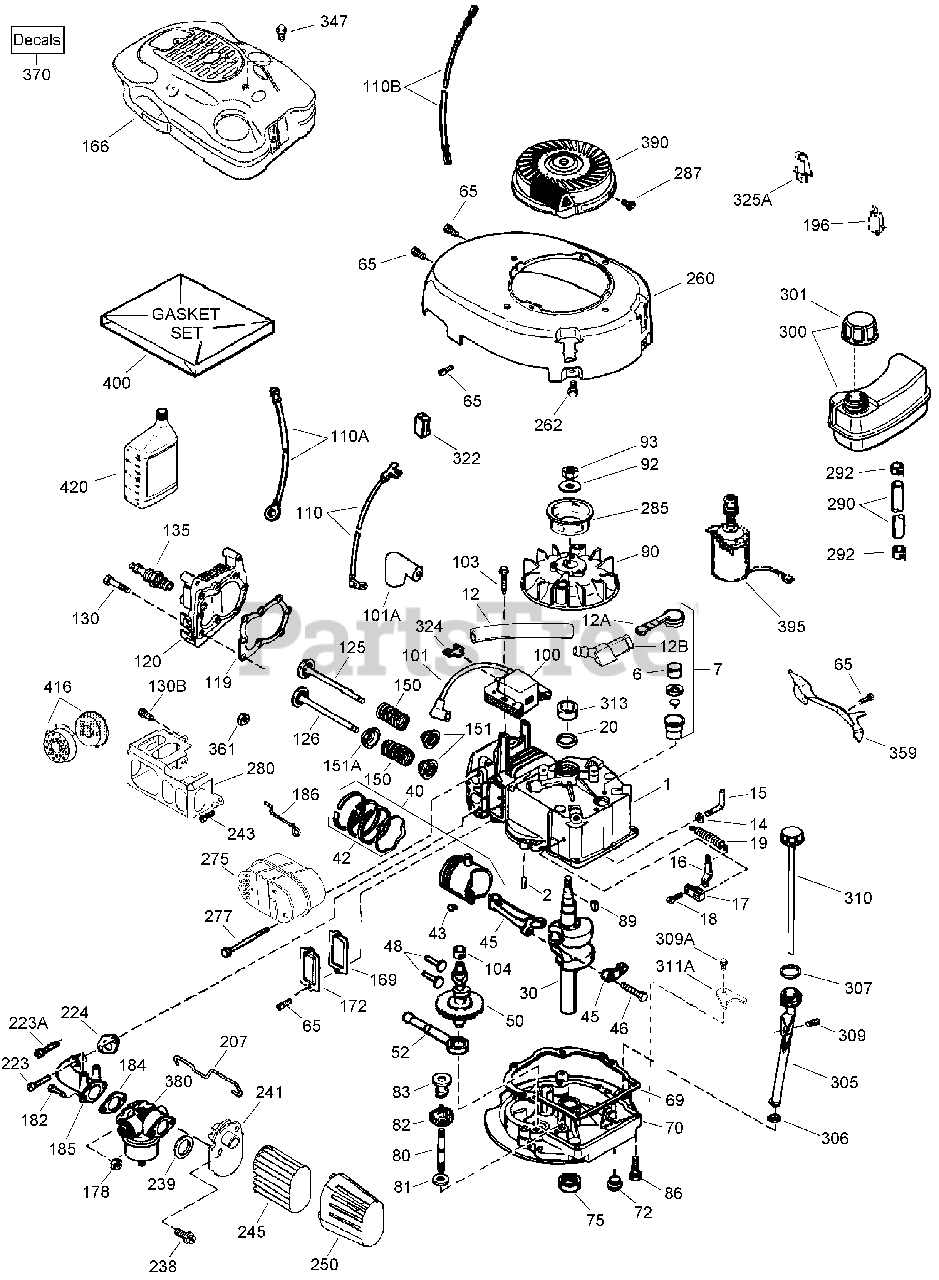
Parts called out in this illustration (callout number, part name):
150	Spring-Valve
151	Cap-Valve, Spring
151A	Seal-Valve, Intake
166	Shroud-Engine (Green)
169	Gasket-Cover, Valve
172	Cover-Valve
178	Nut and Lock Washer (1/4-28)
182	Screw (1/4-28 x 7/8)
184	Gasket-Carburetor To Intake Pipe
185	Pipe-Intake
186	Link-Governor
196	Switch-Restart, Power
207	Link-Throttle
223	Screw (1/4-20 x 1)
223A	Stud-Pipe, Intake
224	Gasket-Pipe, Intake
238	Screw (10-32 x 49/64)
239	Gasket-Air Cleaner
241	Collar-Air Cleaner
243	Screw (10-32 x 7/16)
245	Filter-Air Cleaner (also available in Packaged Part 740083)
250	Cover-Air Cleaner
260	Housing-Blower
262	Screw (1/4-20 x 1/2)
275	Muffler
277	Screw (1/4-20 x 2-9/32)
280	Shield-Heat
285	Cup-Starter
287	Screw (8-32 x 21/64)
290	Line-Fuel (Low Permeation)
292	Clamp-Line, Fuel
300	Fuel Tank ASM (Includes 292 and 301)
301	Cap-Fuel (Black) (1-1/2 ID) (also available in Packaged Part 740041B)
305	Tube-Fill, Oil
306	O-Ring
307	O-Ring
309	Screw (10-32 x 1/2)
309A	Screw (10-24 x 3/4)
310	Dipstick
311A	Bracket-Holddown
313	Spacer
322	Body-Connector
324	Terminal
325A	Clip-Actuator, Brake Switch
347	Screw (10-32 x 27/32)
359	Guard-Flywheel
361	Nut-Lock
370	Decal-Primer
370	Instruction Decal - Caution - read owner's manual
380	Carburetor ASM (Includes 184)
390	Starter-Recoil
395	12-Volt Electric Starter Motor ASM
400	Gasket Set
416	Spark Arrestor Kit (Includes 417)
420	Oil-Engine, SAE 30 (4-Cycle)
